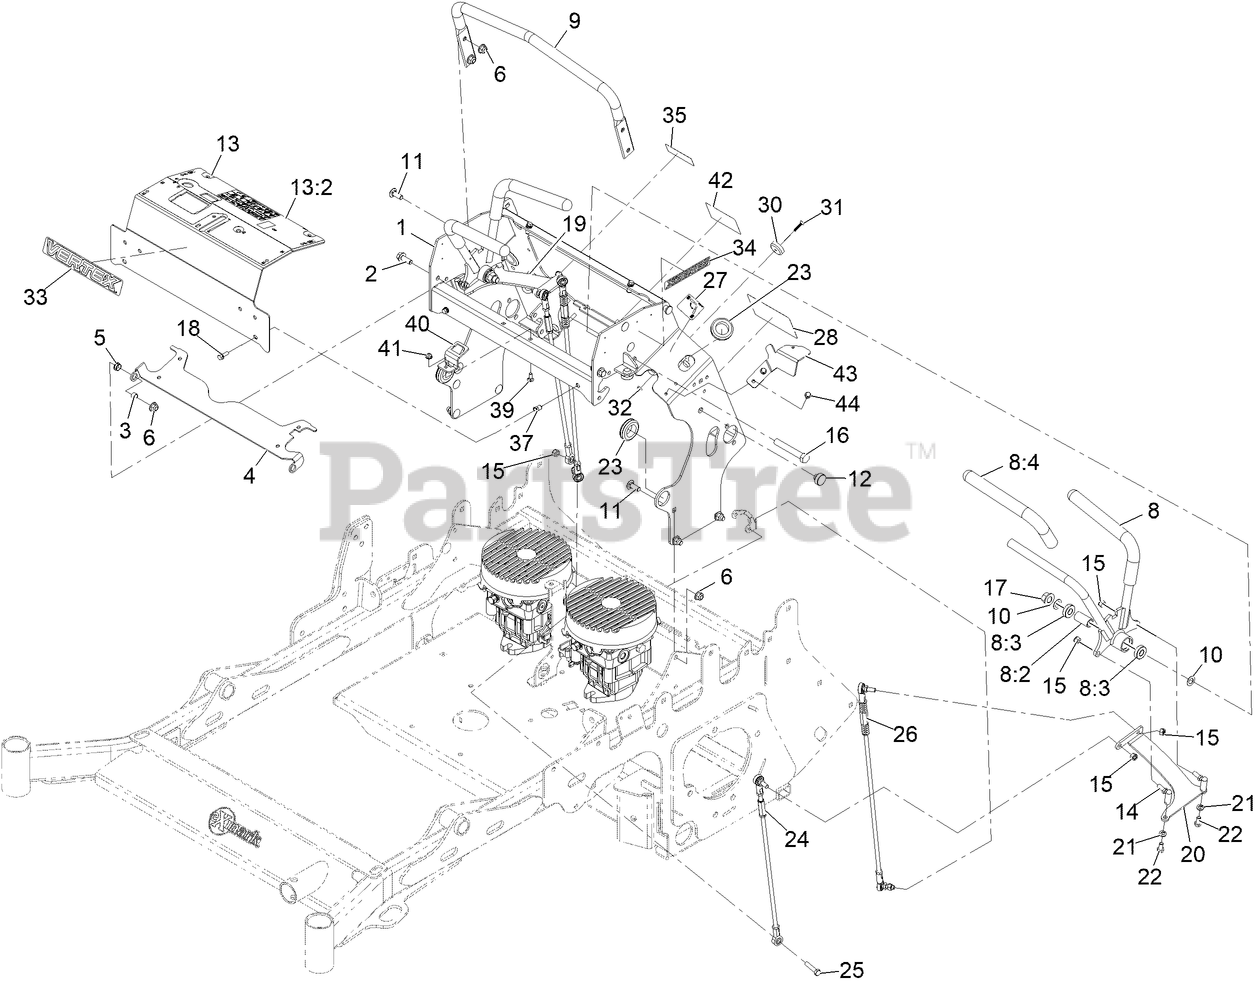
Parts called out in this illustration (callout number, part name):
1	ASM-TOWER
2	SCREW-HHF 3/8-16 X 1
3	SPACER-BRAKE PIVOT
4	PLATE-MOTION CNTRL LOCK
5	BUSHING,SNAP
6	NUT-HF, NI
8	ASM-CTRL LEVER
8:3	BEARING-WHEEL
8:4	GRIP-HANDLE, CONTROL
9	BAR-REFERENCE
11	SCREW-CARR
12	BUMPER-RUBBER
13	ASM-CONTROL PANEL W/DCL
13:2	DECAL-CONTROL PANEL
14	BALLJOINT-RH (W/GROMMET)
15	NUT-LOCK
16	SCREW-HH
17	Nut-Lock 1/2-13
18	SCREW-HHF
19	BRACKET-LINK CTRL LH
20	BRACKET-LINK CTRL RH
21	WASHER-LOCK
22	SCREW-HH
23	GROMMET
24	ASM-MOTION CONTROL SHORT
25	SCREW-HH
26	ASM-MOTION CONTROL LONG
27	DECAL-PARK BRAKE, CE
28	DECAL-SERVICE AID
30	MAGNET-RARE EARTH THIGH PAD
31	SCREW FLAT HD #10-24X1.00
32	NUT-LOCK
33	DECAL-VERTEX LOGO
34	DECAL-X-SERIES
35	DECAL-FUSE
37	Nut-Clinch, Hex
39	SCREW-CARR
40	BRACKET-BRAKE SWITCH
42	DECAL-DRIVE RELEASE
43	BRACKET-FUEL LINE CLAMP LH
44	SCREW-HWH
